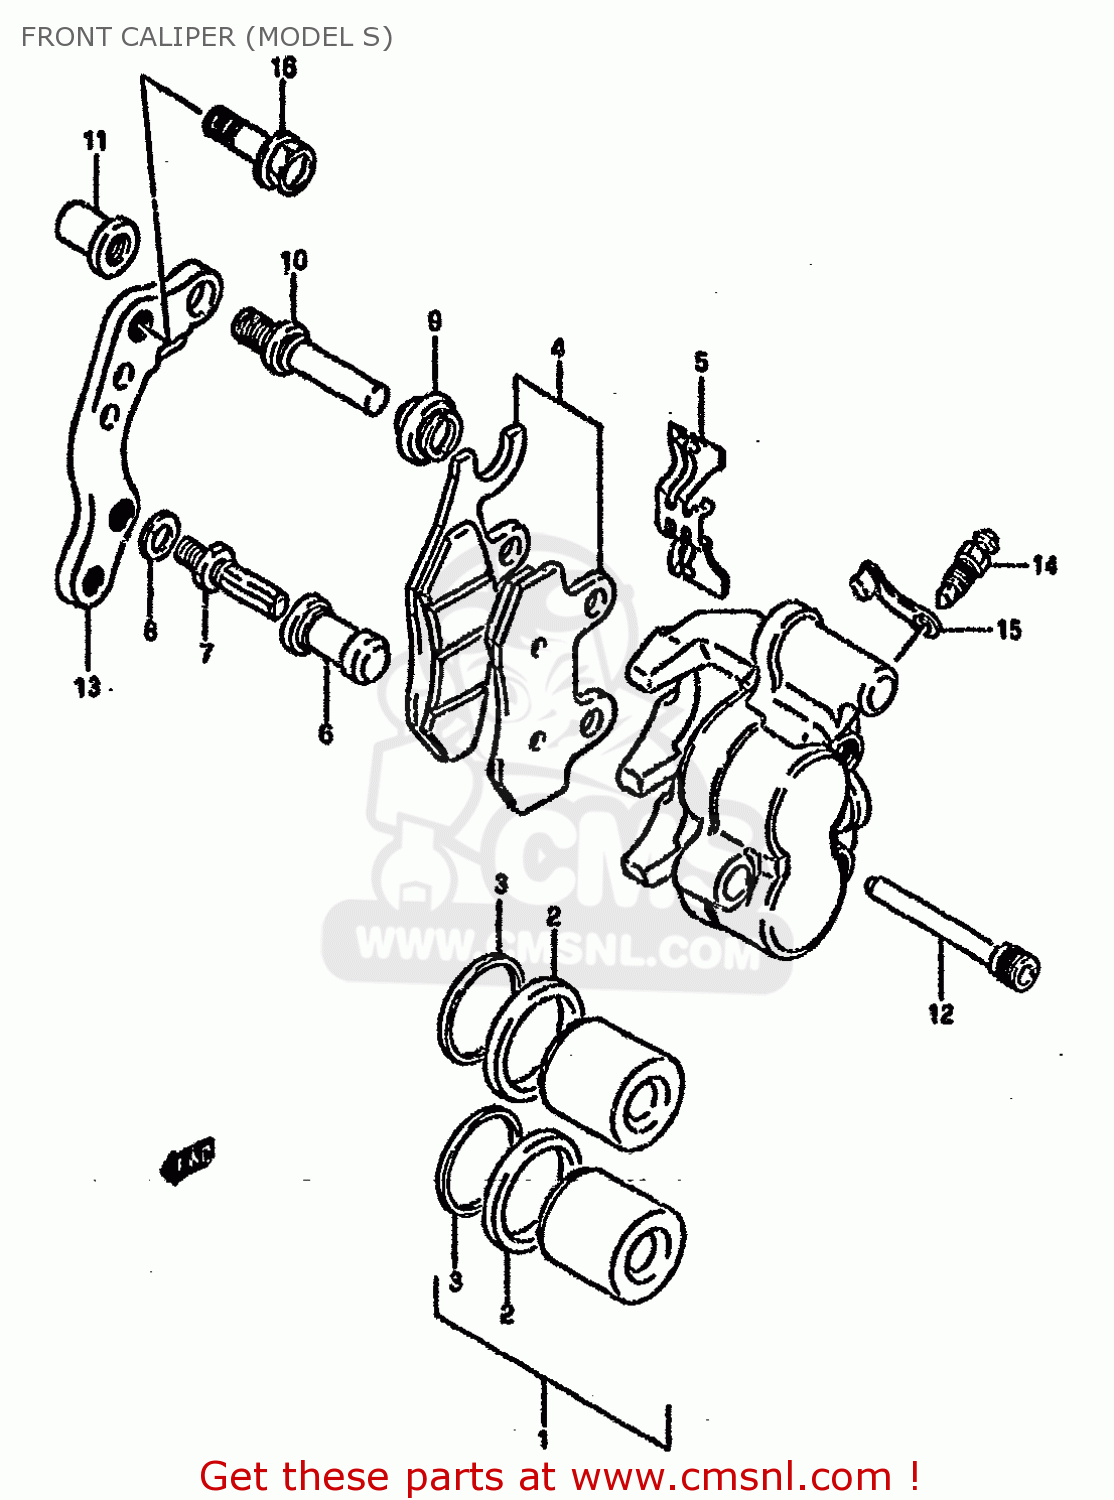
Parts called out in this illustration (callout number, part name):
1	PISTON SET
2	SEAL,PISTON
3	SEAL,DUST
4	PAD SET (NAS)
5	SPRING,PAD
6	BOOT
7	BOLT,PIN
8	WASHER
9	BOOT
10	PIN,SLIDE
11	NUT
12	PIN,HOLDER
13	BRACKET
14	BLEEDER
15	CAP,BLEEDER
16	BOLT,FRONT CALIPER
